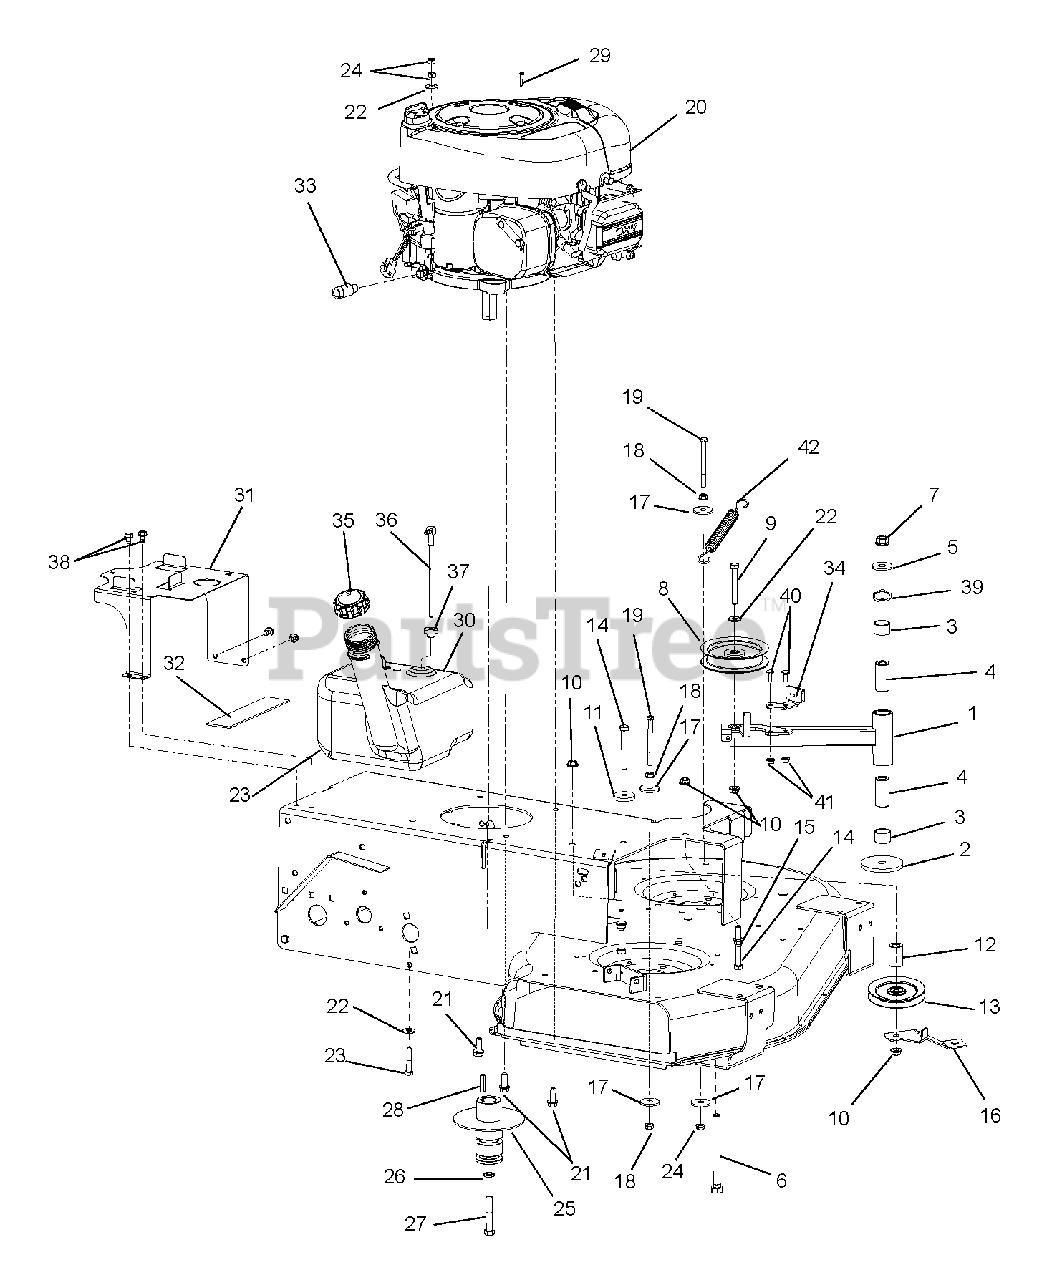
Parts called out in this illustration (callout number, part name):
1	Weldment, PTO Idler Arm
2	Washer, Flat .531 x 3.00 x .25
3	Bearing 1.00 x 1.12 x .75
4	Bushing, Spacer .505/.500 x .999/.996 x 2.05/2.03
5	Washer, Flat Steel .511 x 1.44 x .125
6	Bolt, Hex .50-13 x 5.50
7	Nut, Locking Top Flange .50-13
8	Idler, Flat .38 x 4.00 x 1.06
9	Bolt, Hex .38-16 x 2.75
10	Nut, Locking Top Flange .38-16
11	Washer, Flat Steel .406 x 1.50 x .245
12	Spacer, .437 x 1.00 x 1.23
13	Idler, 4.00 x .38
14	Bolt, Hex .38-16 x 3.00
15	Nut, Flange .375-16
16	Bracket, Idler Brace
17	Washer, Flat Steel .406 x 1.375 x .135
18	Nut, Spin-Lock Flange .312-18
19	Bolt, Hex .31-18 x 3.50
20	Engine, Briggs & Stratton, 14.5Hp
21	Screw, Hex Washer Head Tapping .38-16 x 1.00 (Torque = 374 – 562 lbf-in (42.26 – 63.5 Nm))
22	Washer, Flat Steel .38 x .875 x .083
23	Bolt, Hex .31-18 x 1.75
24	Nut, Locking Center .31-18
25	Pulley, Deck Drive
26	Washer, Locking .44 x .109
27	Bolt, Hex .44-20 x 2.50 (Torque = 394 – 590 lbf-in (44.52 – 66.66 Nm))
28	Key, Square .25 x 1.25 x .25
30	Tank, Fuel
31	Bracket, Gas Tank Mount
32	Pad, Gas Tank
33	Drain, Oil
34	Brake Pad Assembly
35	Fuel Cap
36	Assembly, Pickup, Fuel 6.5L
37	Bushing, Flange .375 x 1.062 x .625
38	Screw, Tapping .31-18 x .50 Hex Washer Head
39	Washer, Wave 1.09 x 1.37 x .016
40	Bolt, Round Head Square Neck .25-20 x .75 Grade 5
41	Nut, Locking-Top-Flange .25-20
42	Spring, Engine, Transmission
